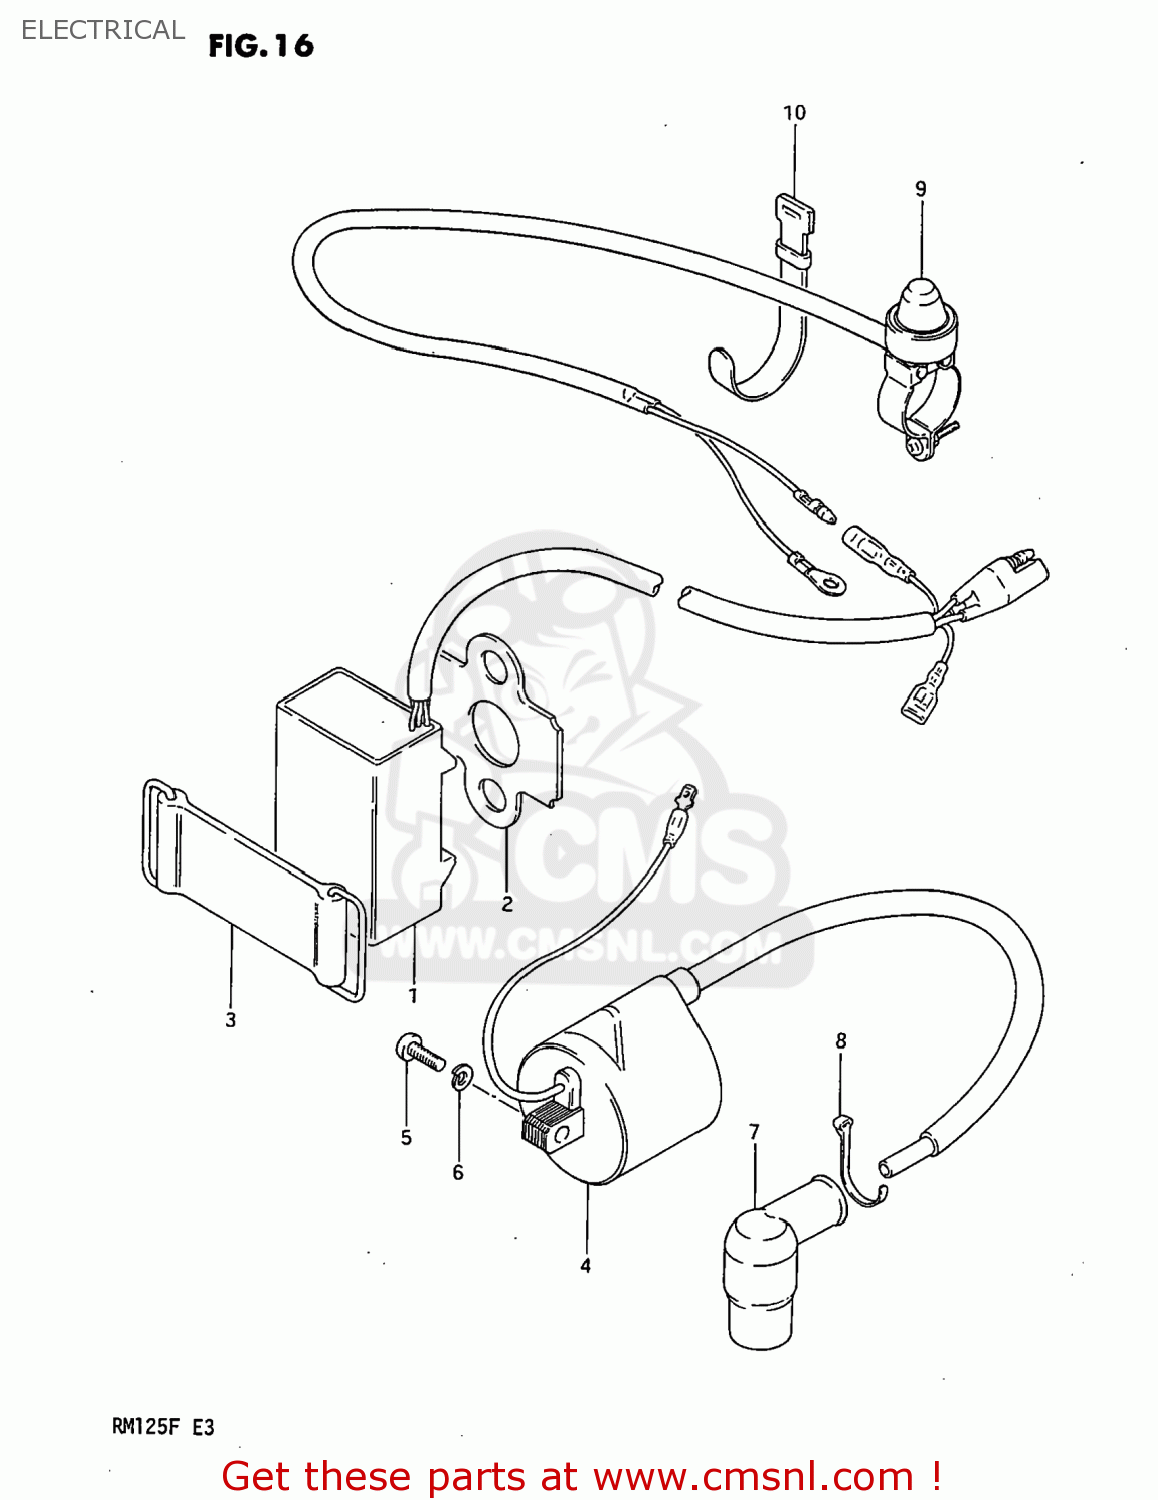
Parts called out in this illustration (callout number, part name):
1	CDI UNIT
2	PROTECTOR,CDI UNIT
3	BAND
4	COIL ASSEMBLY,IGNITION
5	SCREW
6	LOCK WASHER
7	CAP,SPARK PLUG
8	CLAMP
9	SWITCH ASSEMBLY
10	CLAMP(L:120)
